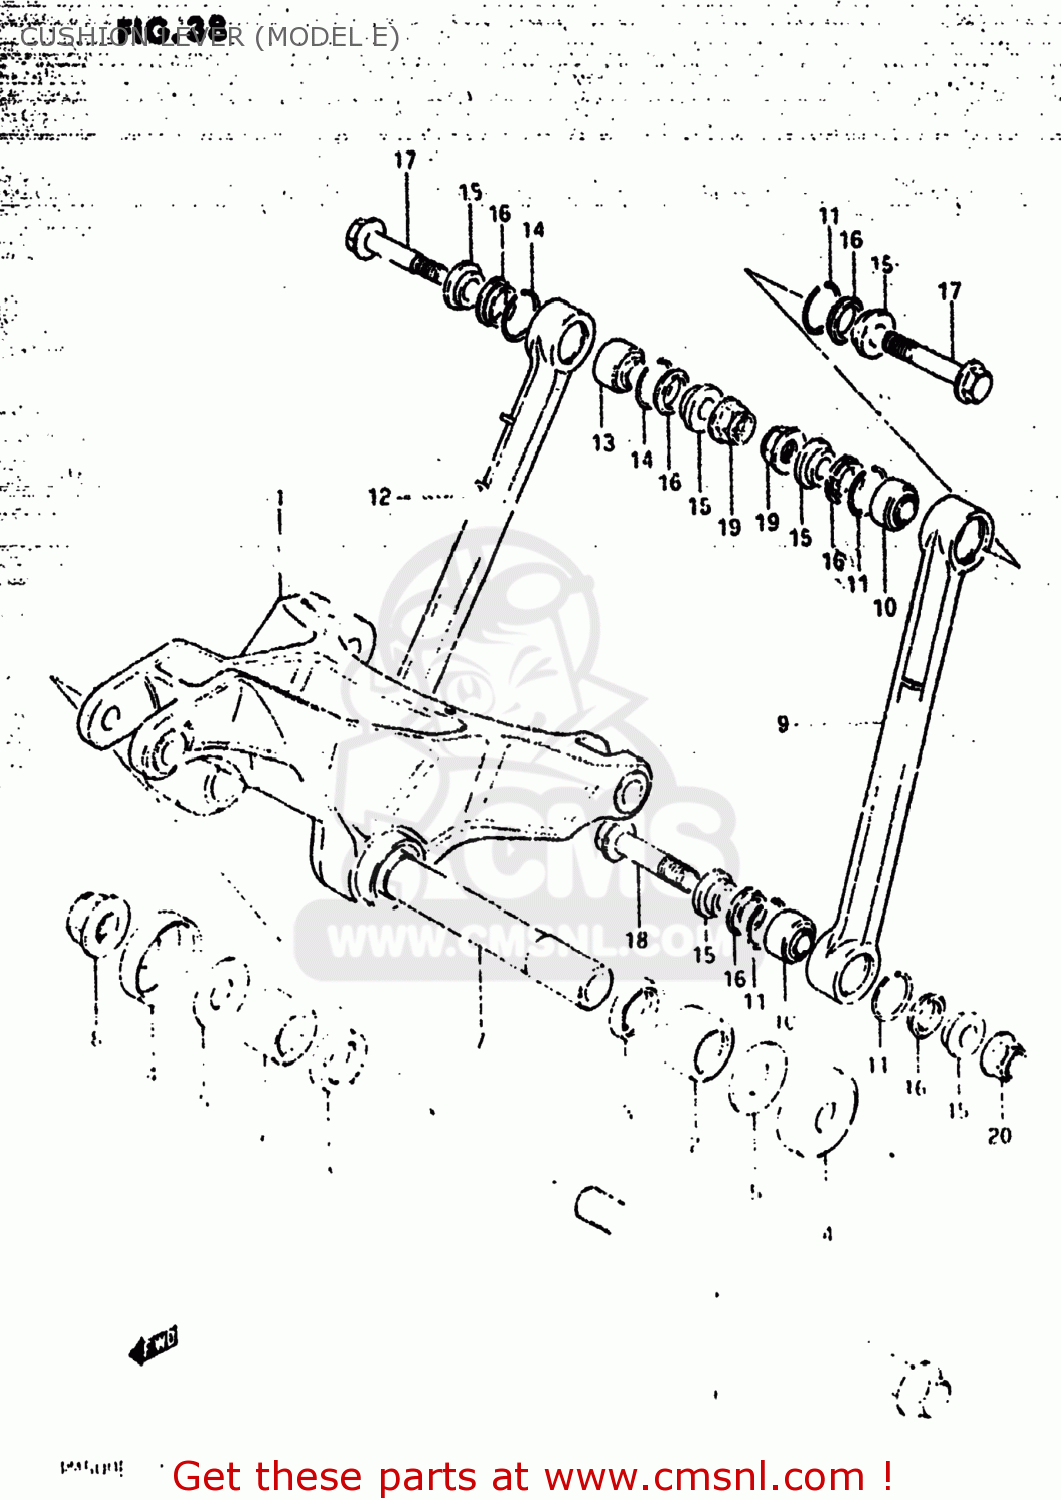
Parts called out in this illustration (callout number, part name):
1	LEVER SET,REAR CUSHION
2	BEARING(20X27X25)
3	SEAL,CUSHION LEVER DUST
4	CVR,RR SWGARM DUST SEAL(OD:40)
5	WASHER
6	SHAFT,REAR CUSHION LEVER
7	SPACER,REAR CUSHION LEVER
8	NUT
9	LEVER SET,REAR CUSHION
10	BEARING(10X21X13)
11	RING,BEARING STOPPER
12	LEVER SET,REAR CUSHION
13	BEARING(10X21X13)
14	RING,BEARING STOPPER
15	SPACER,REAR CUSHION ROD
16	SEAL,RR CUSHION ROD DUST
17	BOLT,REAR CUSHION ROD
18	BOLT,RR CUSHION ROD LWR
19	NUT
20	NUT
